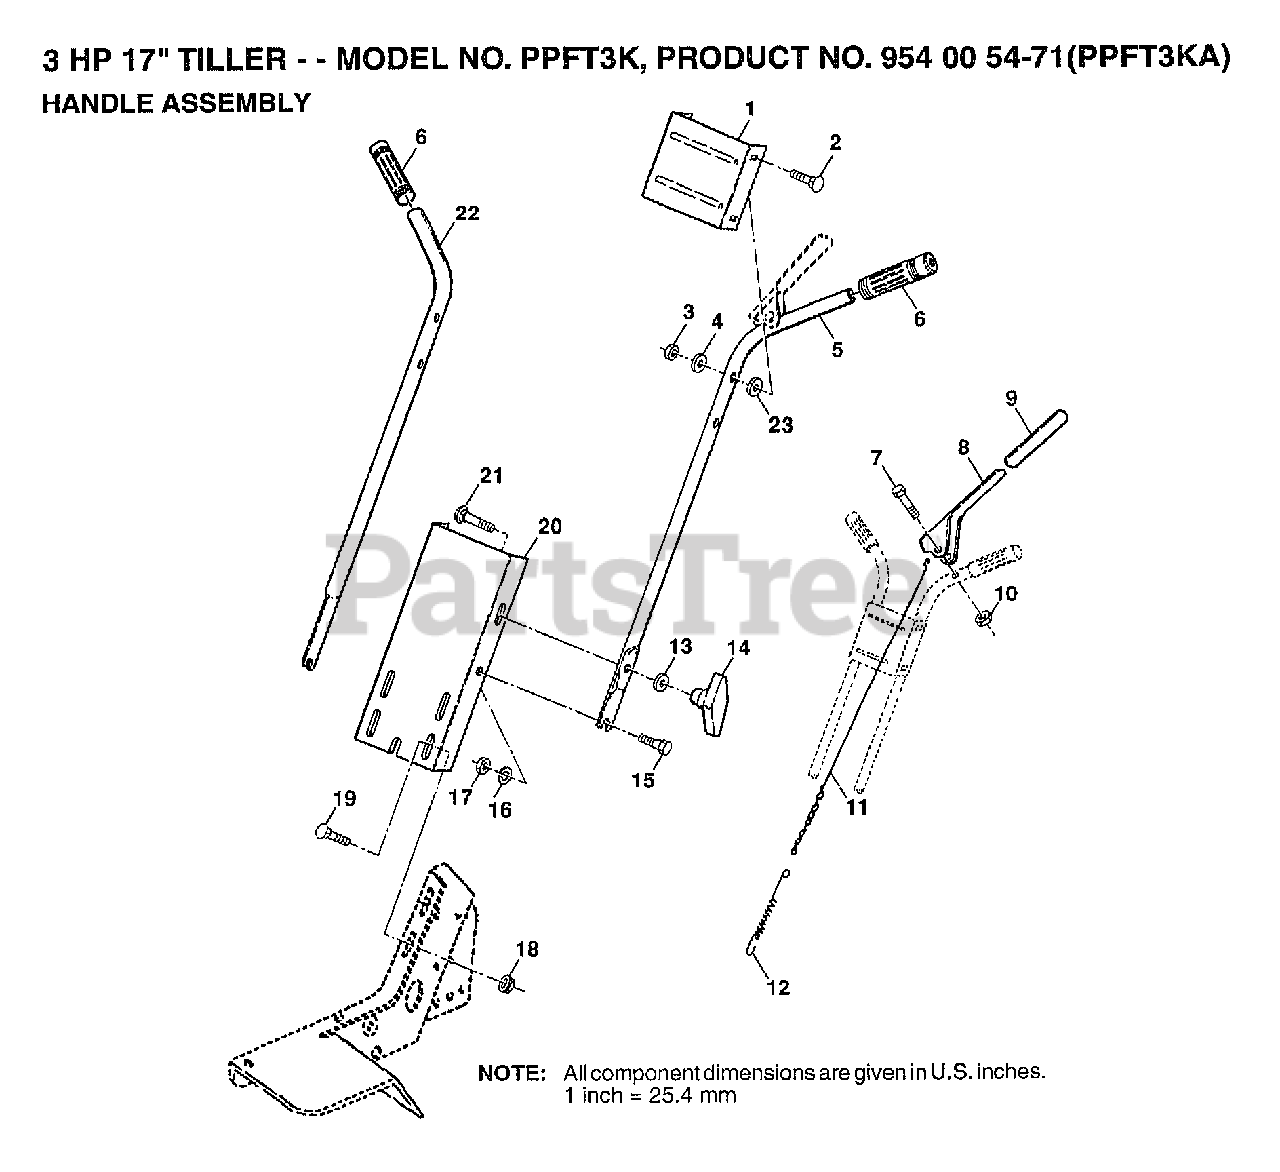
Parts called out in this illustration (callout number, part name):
2	BOLT, CARRIAGE
3	LOCKNUT, CROWN 5/16-18
4	WASHER 11/32 X 11/16 X 16 GA.
7	BOLT, HEX 5/16-18 X 1-1/2
13	WASHER 3/8 X 7/8 X 14 GA.
18	NUT, FLANGED
19	BOLT, CARRIAGE
21	BOLT, CARRIAGE 5/16-18 X 1
23	WASHER
